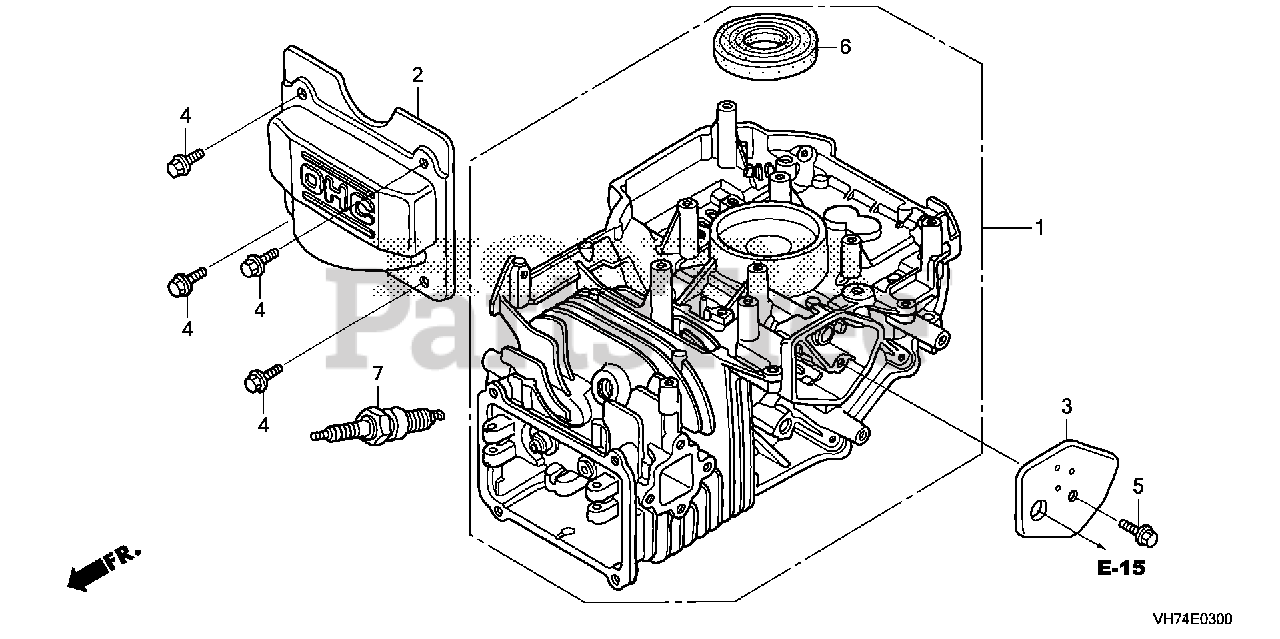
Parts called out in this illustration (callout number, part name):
1	CYLINDER ASSY.
2	COVER, HEAD
3	COVER, BREATHER (BREATHER VALVE ASSY.)
4	BOLT, FLANGE (6X12) (CT200)
5	BOLT, FLANGE (6X14) (CT200)
6	OIL SEAL (25.4X62X6)
7	SPARK PLUG (BPR5ES) (NGK)
